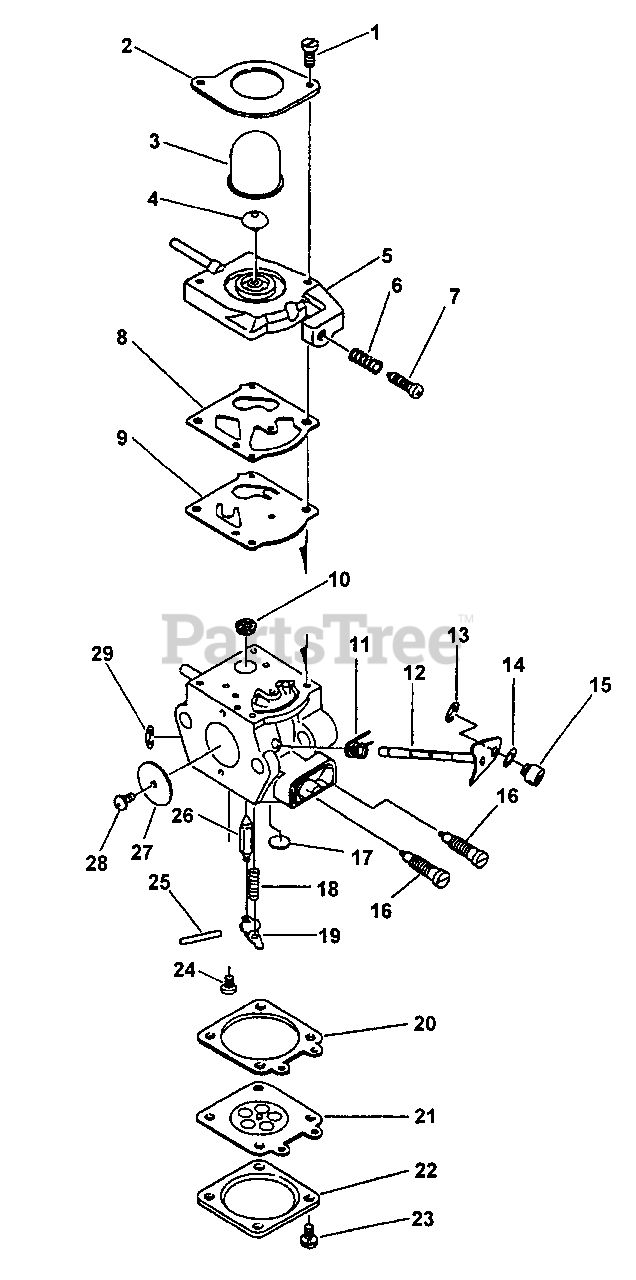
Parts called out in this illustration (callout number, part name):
1	SCREW, PUMP COVER
2	RETAINER, PURGE BULB
3	BULB, PURGE
4	VALVE, CHECK
5	BASE, PURGE
6	SPRING, IDLE ADJUST
7	SCREW, IDLE ADJUST
8	GASKET, PURGE
9	DIAPHRAGM, PURGE
10	STRAINER
11	SPRING, THROTTLE RETURN
12	SHAFT, THROTTLE
13	RING, RETAINING
16	NEEDLE - MIXTURE
17	PLUG, WELCH
18	SPRING, METERING LEVER
19	LEVER, METERING
20	GASKET, METERING
21	DIAPHRAGM, METERING
22	COVER, METERING
23	SCREW
24	SCREW
25	PIN, METERING LEVER
26	VALVE, INLET NEEDLE
27	VALVE, THROTTLE
29	RING, RETAINING
